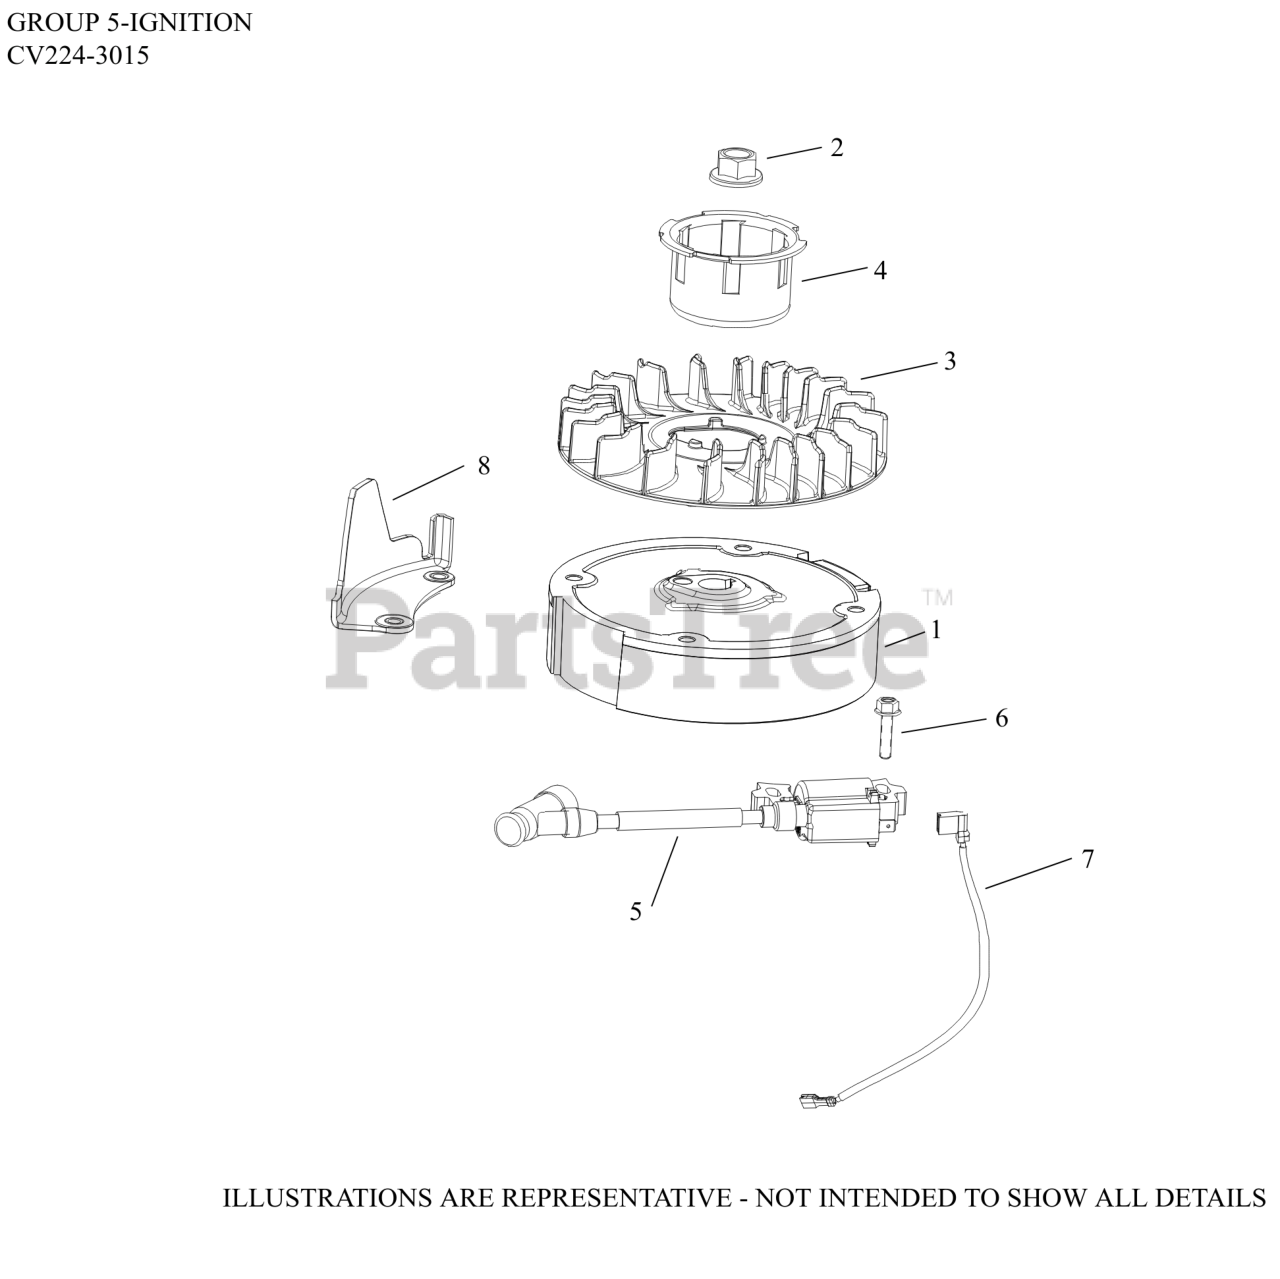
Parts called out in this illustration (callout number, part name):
1	FLYWHEEL (CAST IRON)
2	NUT, FLYWHEEL (W/SERRATIONS)
3	FAN, FLYWHEEL
4	CUP, STARTER DRIVE
5	MODULE IGN (#1458416S)
6	SCREW, M6 X 25-(#25086436S)
8	GUARD, FINGER
